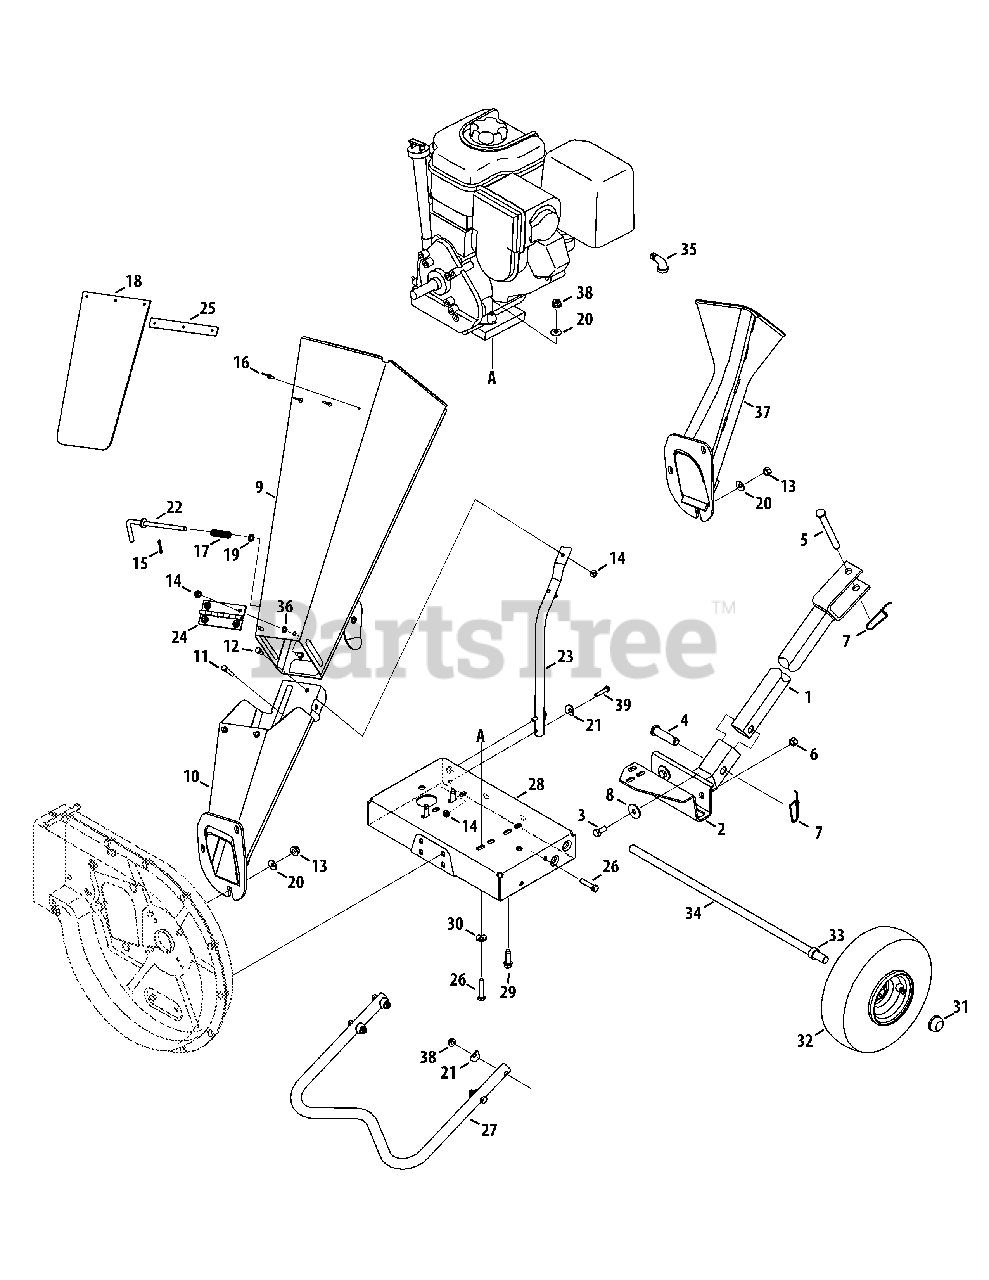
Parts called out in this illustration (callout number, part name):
2	Base Hitch Mount
3	Hex Cap Screw, 3/8-16 x.88
4	Clevis Pin,.625 x 2.4
5	Clevis Pin,.50 x 4.62
6	Flange Lock Nut, 3/8-16
7	Spring Pin
8	Flat Washer,.411 x 1.25 x 1.0
9	Upper Chipper Chute Assembly
10	Lower Chipper Chute Assembly
11	Hex Cap Screw, 1/4-20 x 1.25
12	Screw, 1/4-20 x .50
13	Hex Nut, 5/16-18
14	Flange Lock Nut 1/4-20
15	Cotter Pin
16	Pop Rivet
17	Compression Spring,.531 x 1.75
18	Chute Flap
19	Flat Washer
20	Bell Washer.340 ID x.872 OD
21	Washer,.320 ID x.93 OD
22	Lock Rod
23	Chipper Chute Support
24	Chipper Chute Hinge
25	Chute Flap Strip
26	Hex Cap Screw, 5/16-18 x 1.50
28	Frame Assembly
29	Hex Sems Screw, 3/8-16 x 1.25
30	Special Lock Washer, 5/16
31	Push Cap, 5/8
32	Wheel, 10 x 4 x 4
33	Spacer, .64 x .88 x .38
34	Axle, 22.47"
35	Elbow Fitting
36	Push Nut,.25ID x.50OD
37	Chipper Chute
38	Flange Lock Nut, 5/16-18
39	Hex Cap Screw, 1/4-20 x 1.250
